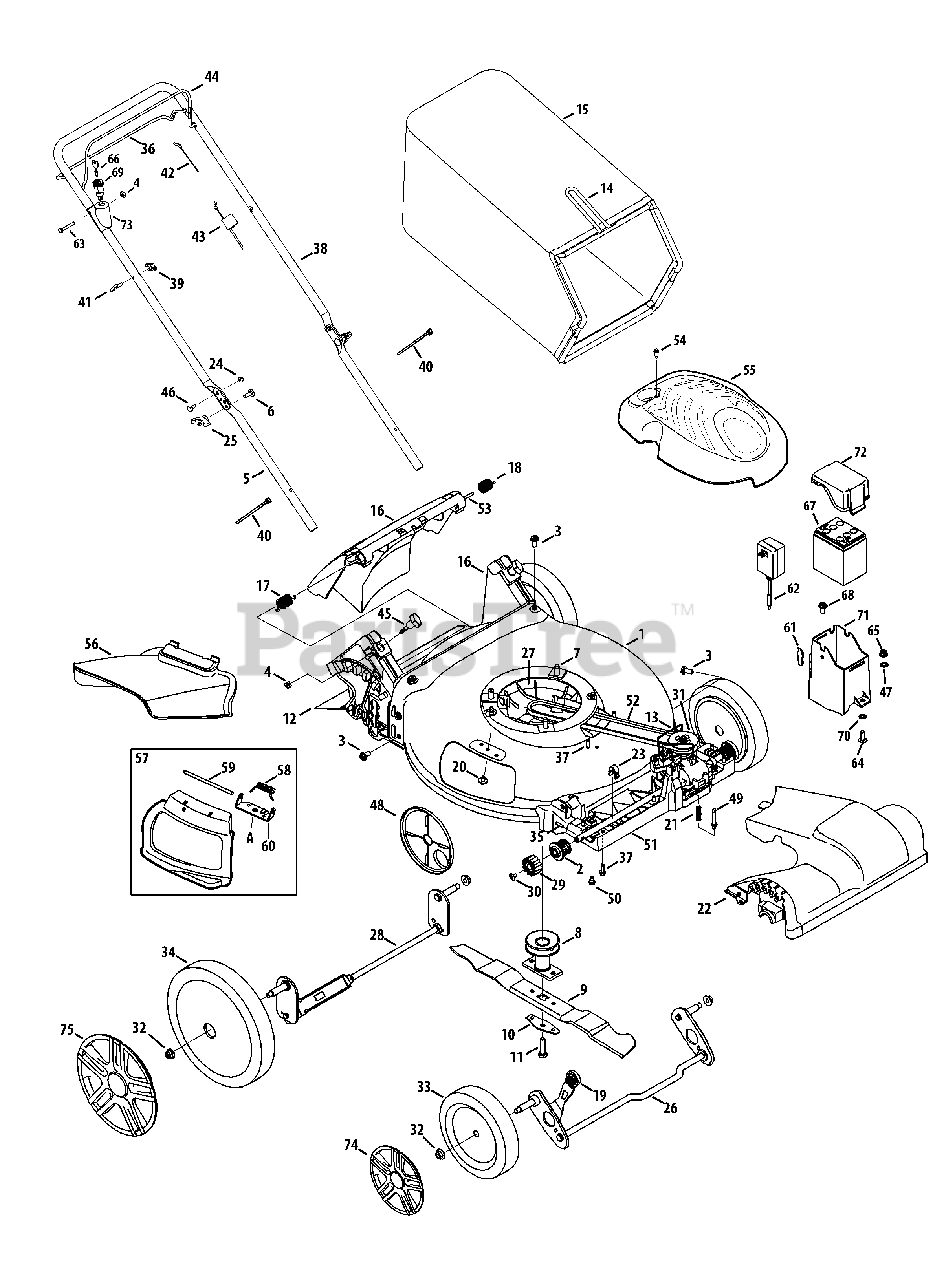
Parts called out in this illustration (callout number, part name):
1	Deck, 21"
2	Bearing Assembly
3	Screw, 5/16-14 x .750
4	Nut, Sq., 1/4-20
5	Lower Handle
6	Carriage Screw ,5/16-18
7	Screw, 3/8-16 x 1.00
8	Blade Adapter
9	Mulching Blade
10	Blade Bell Support
11	Screw, 3/8-24 x 1.50
12	Trailing Shield
13	Transmission Wire
14	Grass Catcher Frame
15	Grass Bag (Yardman)
16	Rear Discharge Door Assembly
17	Torsion Spring - RH
18	Torsion Spring - LH
19	Adjustment Lever Knob
20	Screw, 1/4-20 x .500
21	Compression Spring
22	Front Cover
23	Front Axle Clip
24	Nut, Flange Lock, 1/4-20
25	Wing Knob
26	Front Axle Assembly
27	Engine Baffle
28	Rear Axle Assembly
29	Spur Gear, 14T - RH
29	Spur Gear, 14T - LH
30	Screw, 1/4-20 x .390
31	Transmission Assembly
32	Flange Lock Nut, 3/8-16
33	Front Wheel, 8 x 1.8, Bar, Gray
34	Rear Wheel, 11 x 1.75, Bar, Gray
35	Dowel Pin
36	Drive Control
37	Screw, 1/4-15 x .750
38	Upper Handle
40	Cable Tie
41	Rope Guide
42	Control Cable, 40.75
43	Drive Cable
44	Blade Control
45	Wing Nut
46	Sldr. Screw, .375 x .126 x 1/4-20
47	Washer, Bell, .340 x .872 x .080
48	Wheel Dust Cover
49	Spring Body
50	Scr., Shldr., 1/4-20 x .50
51	Lower Tray
53	Pivot Rod
54	Screw, #12-16 x 1.00
55	Engine Shroud, Oyster Gray
56	Side Discharge Chute
57	Mulch Plug (Incl. 58-60)
58	Torsion Spring
59	Hinge Pin
60	Chute Deflector Bracket
61	Lid Seal
62	Battery Charger
63	Screw, 1/4-20 x 1.75
64	Bolt, Carr., 5/16-18 x 1.00
65	Nut, Hexlk, 5/16-18
67	Battery
68	Scr., Sldr., 5/16-14 x .972
69	Key Switch
70	Speed Nut
71	Battery Housing
72	Battery Housing Top
73	Electric Start Housing
74	Hubcap, 8"
75	Hubcap, 11"
